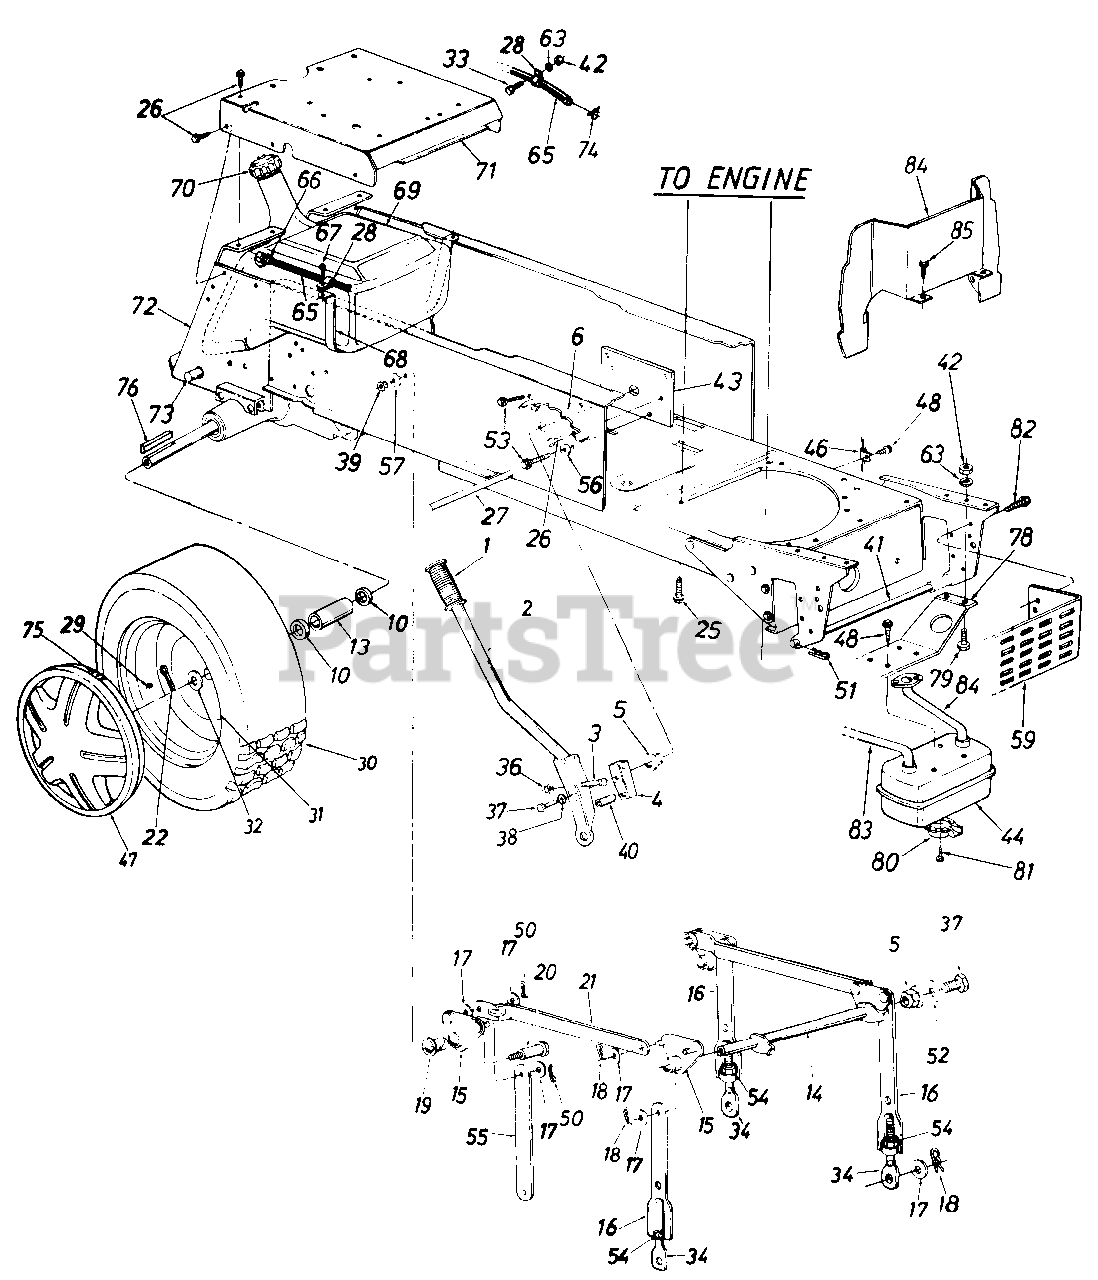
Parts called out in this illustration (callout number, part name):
1	Grip
2	Lift Handle Ass'y.
3	Hex Bolt 5/16-18 x 1.5" Lg.
4	Lift Shaft Drive
5	Plastic Hex Brg. 5/8" I.D.
10	Fl-Wash. 1.03" I.D. x 1.62" O.D.
13	Spacer 1.0" I.D. x 1.25" O.D.
14	Lift Shaft Ass'y.
15	Lift Pivot Brkt. Ass'y.
17	Fl-Wash. 1/2" I.D. x 1.00" O.D. x .090"
18	Hairpin Cotter
19	Nyliner 5/8" I.D. x .88" Lg.
20	Shld. Bolt 5/8" Dia. x .96" Lg. 3/8-16
25	Hex Wash. Hd. Scr. 3/8-16 x 1.25" Lg.
26	Hex Thd. Rolling Scr. 5/16-18 x .75" Lg.
27	Running Board Rod
29	Air Valve
33	Hex Bolt 1/4-20 x .62" Lg.
34	Eye Bolt Adj. Link 1/2-13 Thd.
36	Hex Cent. L-Nut 5/16-18 Thd.
37	Hex Scr. 5/16-24 x .62" Lg.
39	Hex Top L-Nut 3/8-16 Thd.
40	Compression Spring
41	Deck Connecting Rod
42	Hex Nut 1/4-20 Thd.
46	Mounting Clamp
47	Hubcap
48	Hex Wash. Hd. TT-Tap Scr. 1/4-20 x .5" Lg.
50	Cotter Pin .09 Dia. x 1.0" Lg.
51	Int. Cotter Pin
52	Flat Wash. .34" I.D. x 1.12" O.D. x .125"
53	Hex Wash. Hd. AB-Tap Scr. 5/16-24 x .5" Lg.
54	Hex Nut 1/2-13 Thd.
56	Fl-Wash. .344" I.D.
57	Bell-Wash. .4" I.D. x 1.13" O.D.
59	Heat Shield
63	L-Wash. 1/4" I.D.
65	Fuel Line 46" Lg.
67	Hex AB-Tap Scr. 1/4 x .62" Lg.
68	Fuel Tank Strap
69	Gas Tank
75	Spring Clip
76	Sq. Key 1/4" x 3" Lg.
78	Muffler Mounting Brkt.
79	Hex Bolt 1/4-20 x .62" Lg.
80	Muffler Deflector
81	Hex Wash. Hd. F-Tap Scr. #8 x .32" Lg.
82	Hex Wash. Hd. TT-Tap Ser. 5/16-18 x .62" Lg.
83	Exhaust Tube - R.H.
84	Exhaust Tube - L.H.
